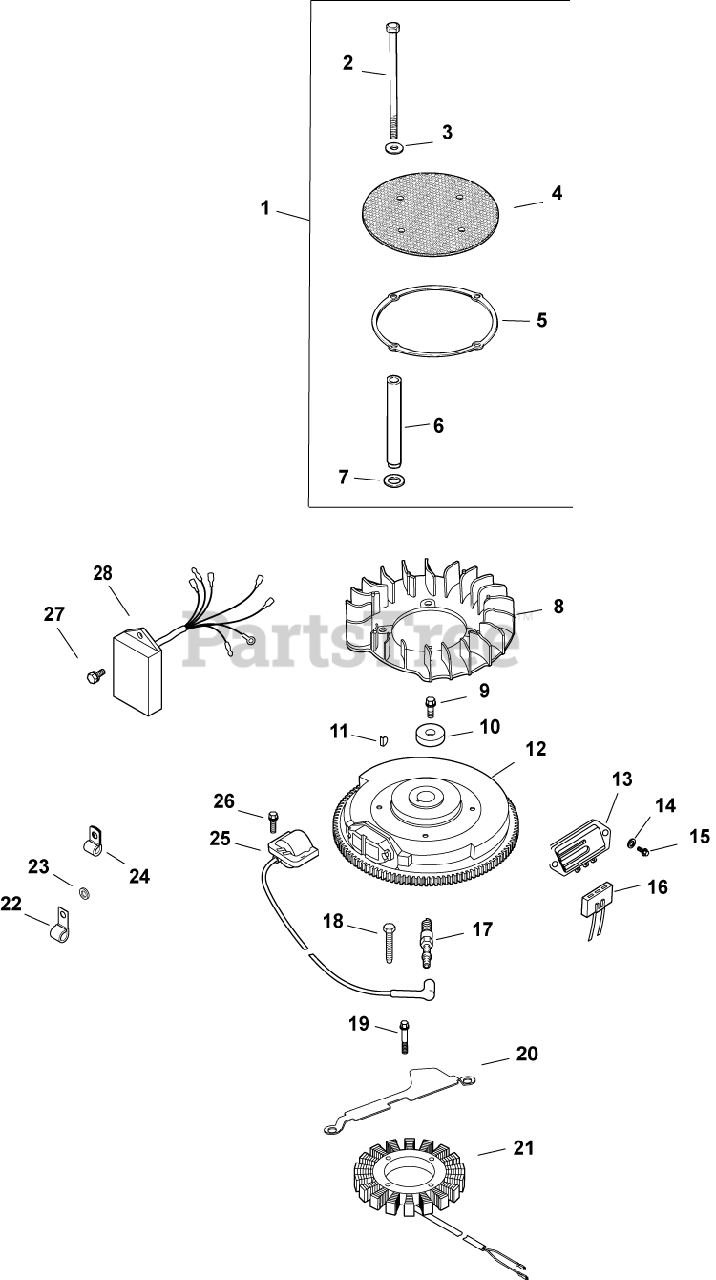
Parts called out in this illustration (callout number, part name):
1	KIT, CHOPPER SCREEN
2	SCREW, CAP M6X1.0X99.5
3	WASHER, FLAT 1/4" (O.D. 5/8")
4	SCREEN, GRASS
5	RING, SUPPORT USE 25 141 08-S
7	WASHER, SPRING 10 MM
8	FAN (DOMED)-USE 24 157 17-S
9	SCREW, FLG M10X1.5X45 - (#25086361S)
10	WASHER, FLAT 13/32"
11	KEY, 3/16" X 5/8"
12	FLYWHEEL, PAINTED-USE 24 025 57-S
13	REG/RECT-15 AMP (KM)-USE 41 403 10-S
14	WASHER, FLAT 3/16"
15	SCREW, PHL HD #11-16X7/8"
16	CONNECTOR, BODY (KM)-USE 25 155 41-S
17	PLUG, SPARK (STD)
18	SCREW, M5X0.8X25 - (#25086402S)
19	SCREW, SKT SET #10-24X1/4"
20	BRACKET, STATOR WIRE
21	KIT, 15 / 20 AMP STATOR
22	CLIP, CABLE
23	WASHER, FLAT 1/4" (O.D. 1/2")
25	MODULE, IGNITION
26	SCREW, FLG THD FRM M5X.8X20-(#25086399S)
27	SCREW, THD FRM M4X0.7X10
28	MODULE, SPEED ADVANCE
